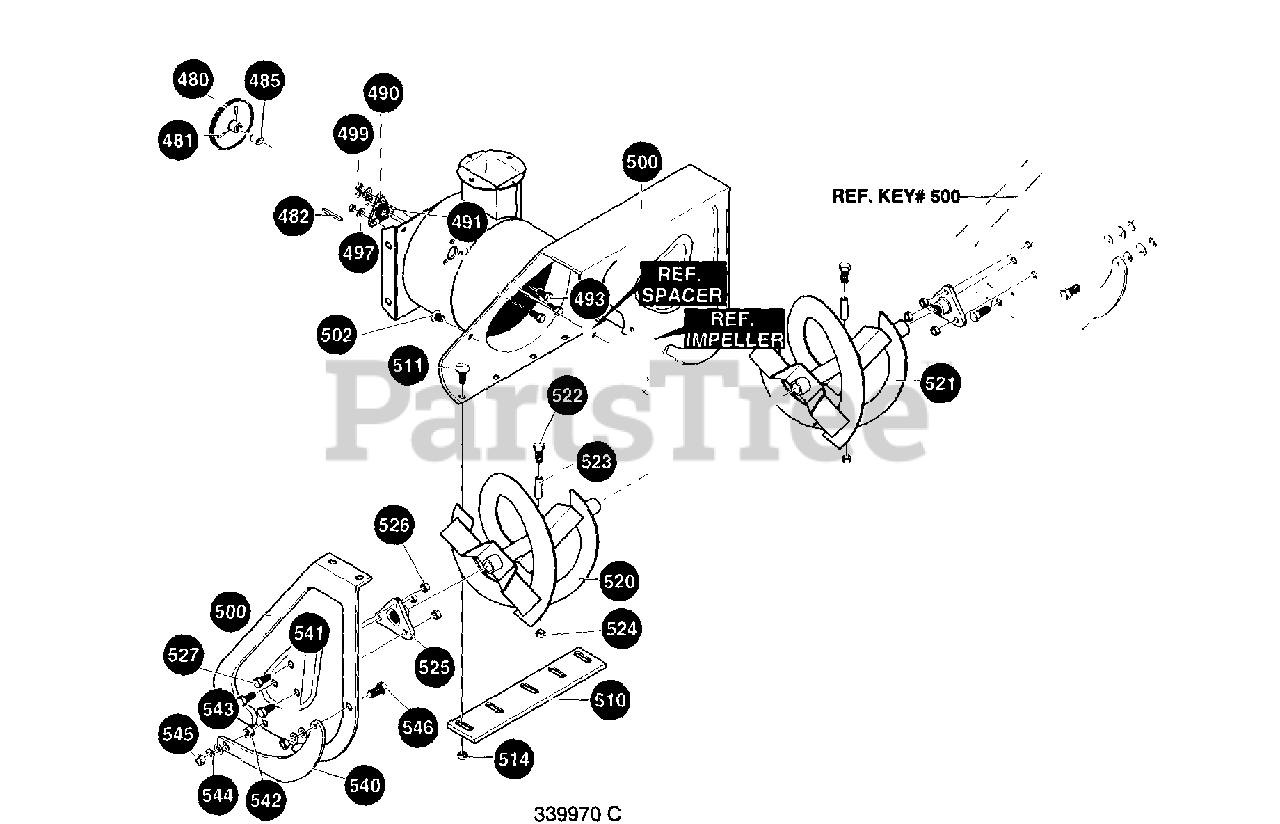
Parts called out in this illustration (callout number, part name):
480	Pulley, V4L
481	Screw, 5/16-18 x .50
482	Key, Square
485	Spacer, Slve .676 x 1.00 x .53
490	Retainer, Ball Bearing
491	Bearing, Ball
493	Screw, 5/16-18 x .75
497	Washer, .328 x .60 x .09
499	Nut, 5/16-18
500	Housing, Assy
502	Ratchet Fastener
510	Blade, Scraper 22"
511	Carr. Bolt, 1/4-20 x .75
514	Nut, 1/4-20 Whiz-loc
520	Auger, Assy RH
521	Auger, Assy LH
522	Screw, 1/4-20 x 1.75
523	Spacer, Slve 250 x .47 x .20
524	Nut, 1/4-20
525	Bearing, Flange
526	Nut, 5/16-18
527	Screw, 5/16-18 x .75
540	Skid, Edge Cover
541	Bolt, 5/16-18 x 1.00
542	Flatwasher, .391 x 1.00 x .209
543	Flatwasher, .344 x .69 x .065
544	Washer, Hvsptlk
545	Nut, 5/16-18 Reghex
546	Screw, 5/16-18 x .75
